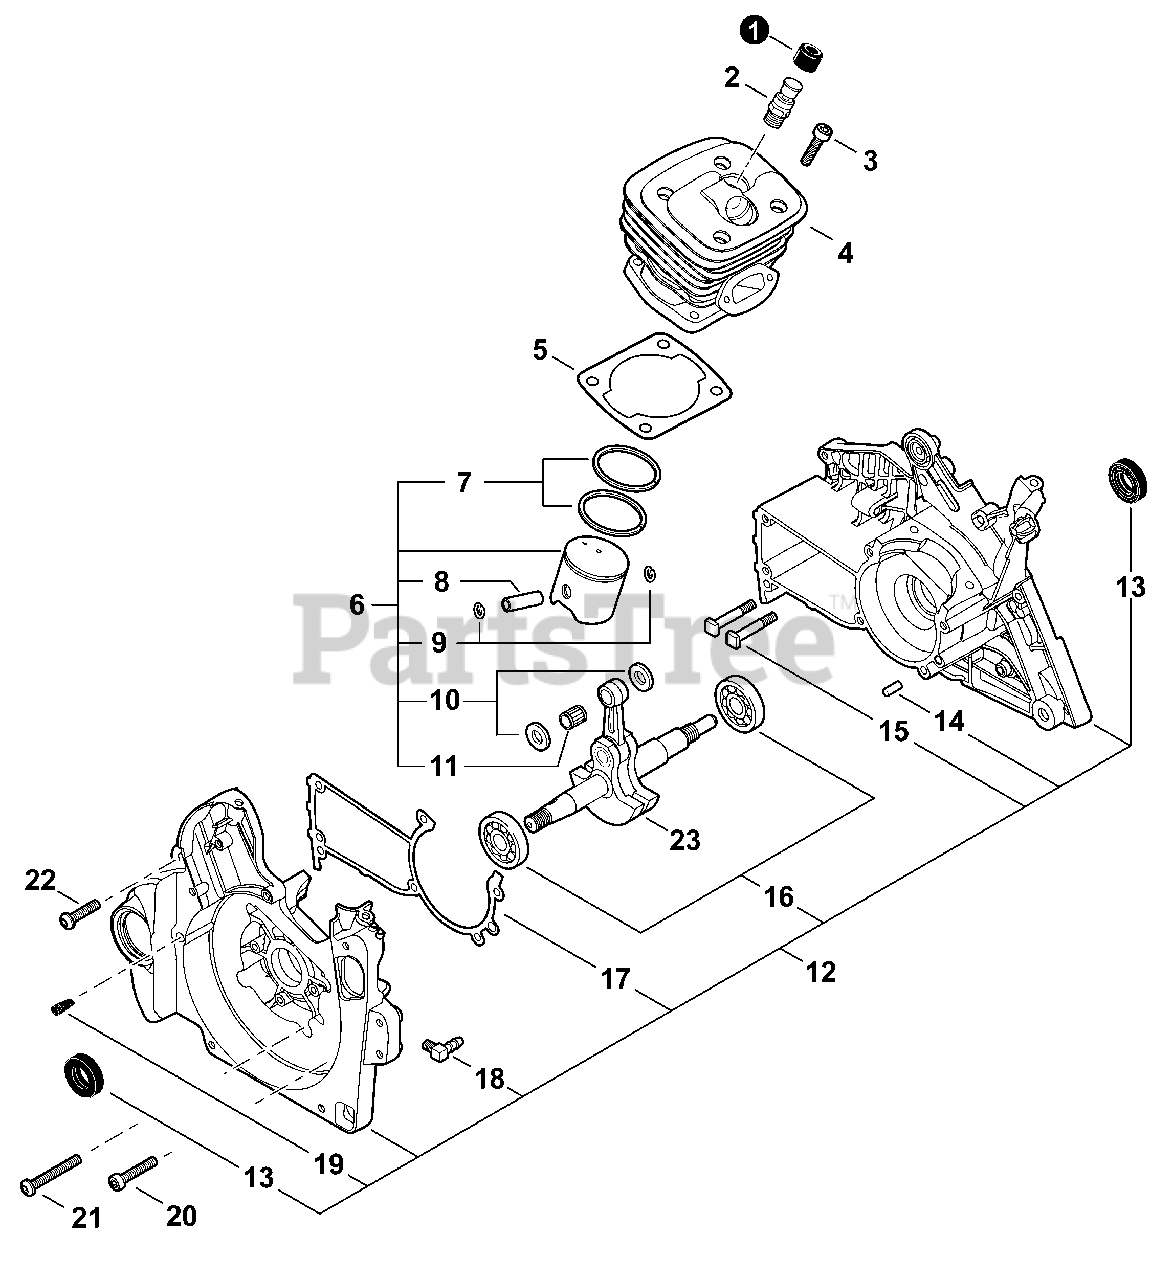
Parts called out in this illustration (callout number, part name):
1	COVER, DUST
2	VALVE ASSY, DECOMPRESSION
3	BOLT, TORX 5×25
4	CYLINDER
5	GASKET, CYLINDER
6	PISTON KIT
7	RING, PISTON
8	PIN, PISTON
9	RING, SNAP Ø11
10	WASHER, THRUST
11	BEARING, NEEDLE 11
12	CRANKCASE KIT
13	SEAL, OIL 15
14	PIN, LOCATING 5×10
15	BOLT, STUD M8×1.25×34.5
16	BEARING, BALL 6202
17	GASKET, CRANKCASE
18	CONNECTOR, PIPE
19	VENT ASSY
20	BOLT, TORX 5×25
21	BOLT, TORX 5×35
22	BOLT, TORX 5×20
23	CRANKSHAFT ASSY
